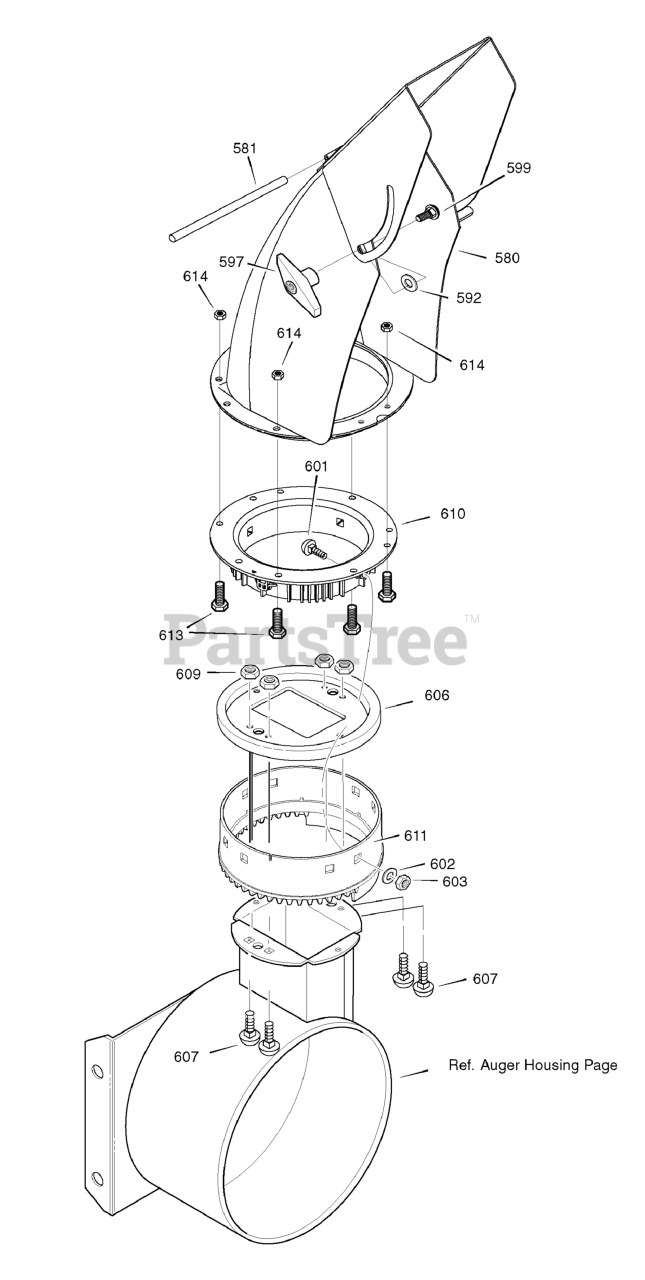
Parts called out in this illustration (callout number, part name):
580	CHUTE ASSEMBLY
592	WASHER, PLASTIC
597	KNOB, T 3.00
599	BOLT, 5/16-18 X .75
601	BOLT, 5/16-18 x 1.00
602	WASHER
603	NUT, 5/16-18 HEXNYL
606	CHUTE COLLAR
607	SCREW, 1/4-20 X .75
609	NUT, 1/4-20 HEX NYLOCK
610	RETAINER RING INNER
611	RETAINER RING OUTER
613	CAPSCREW, Hex-Flange, 1/4-20 x .75
614	NUT, Nylock Flanged, 1/4-20
